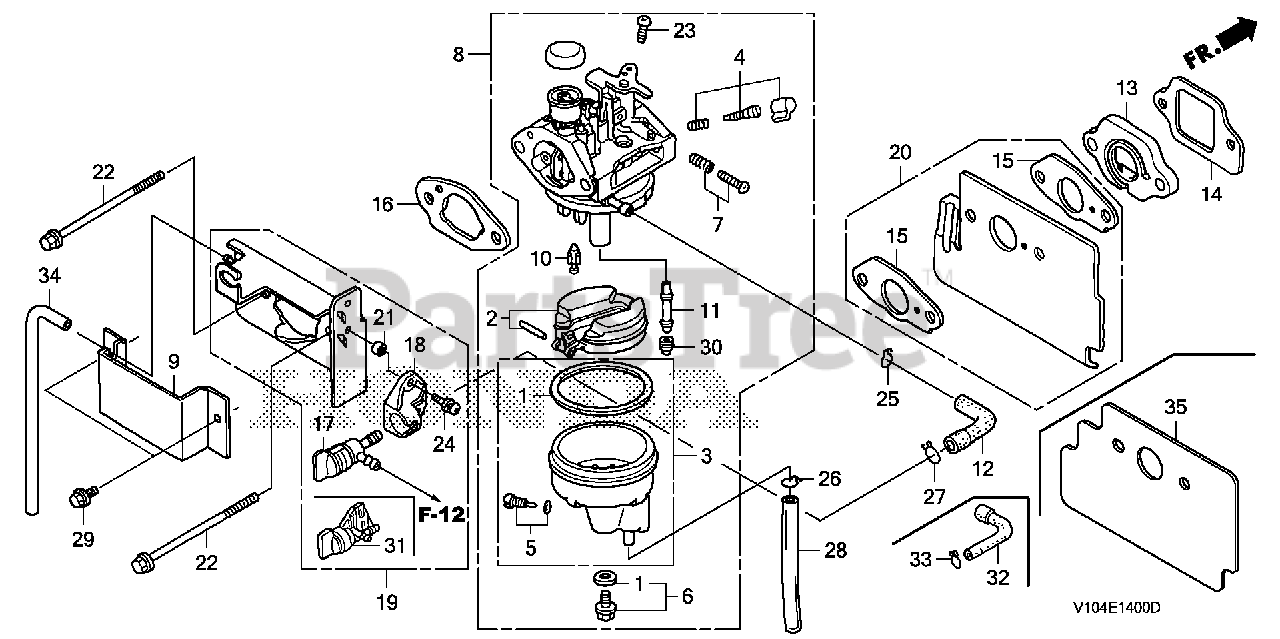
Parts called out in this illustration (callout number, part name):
1	GASKET SET
3	CHAMBER SET, FLOAT
5	SCREW SET, DRAIN
6	SCREW SET
8	CARBURETOR ASSY. (BB70B A)
9	GUARD, CARBURETOR
10	VALVE, FLOAT (CARBURETOR NO.)
11	NOZZLE, MAIN
13	INSULATOR, CARBURETOR
14	GASKET, INSULATOR
16	GASKET, CARBURETOR
19	STAY ASSY., PETCOCK
21	COLLAR, FR. TURN SIGNAL
22	BOLT, FLANGE (6X79) (CT200)
23	SCREW, PAN (5X6)
24	SCREW-WASHER (5X10)
25	CLAMP, TUBE (D8.5)
26	CLIP, TUBE (B6.5)
28	BULK HOSE, VINYL (4X7X8000) (4X7X150)
29	BOLT, FLANGE (6X8)
30	JET, MAIN (#72)
30	JET, MAIN (#75)
30	JET, MAIN (#78)
31	PETCOCK ASSY.
32	TUBE, FUEL (FKM)
33	CLAMP, TUBE (D8)
34	TUBE, AIR VENT
35	GUIDE, AIR
